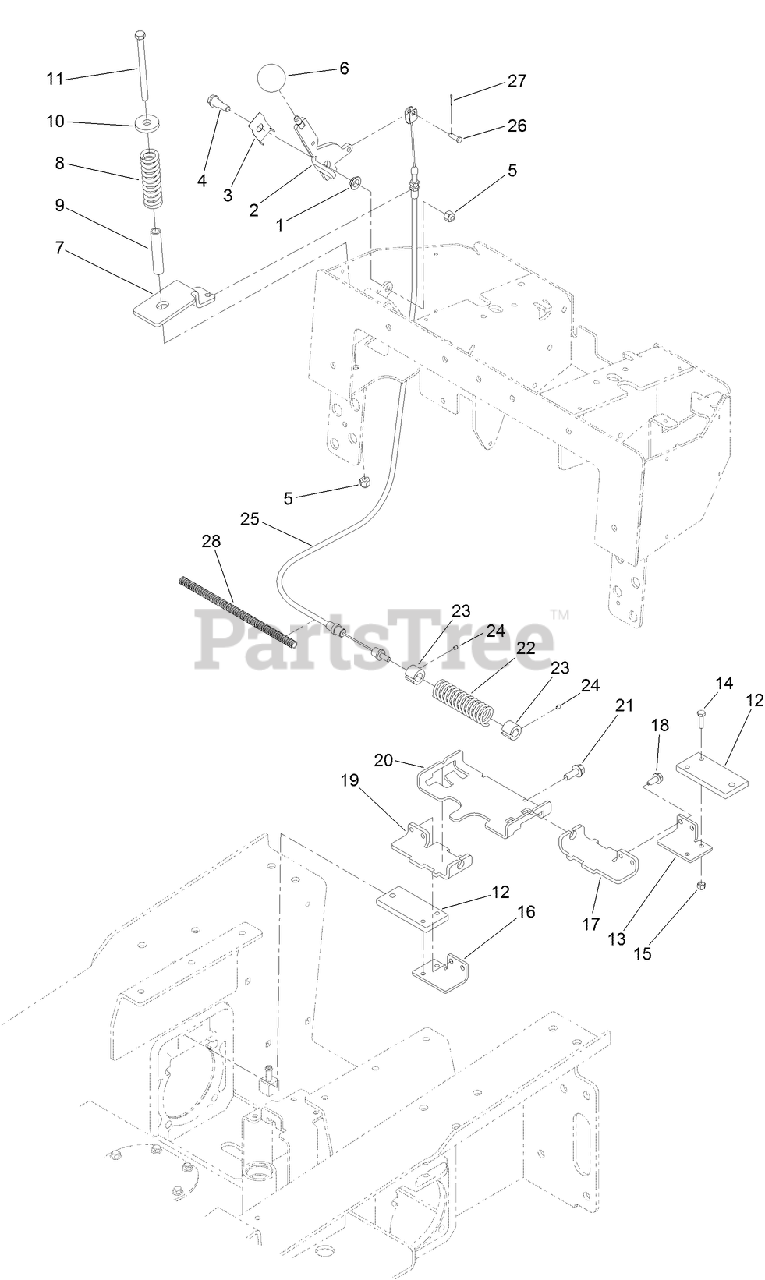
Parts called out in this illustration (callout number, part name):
1	BUSHING-FLANGE
2	HANDLE-BRAKE
3	SPRING-LEAF
4	BOLT-SHOULDER
5	NUT-LOCK, NI
7	BRACKET-CABLE, SPRING
8	SPRING-COMPRESSION
9	SPACER-SPRING
10	WASHER-HARDENED
11	SCREW-HH
12	PLATE-BRAKE
13	BAR-LINK, BRAKE LH
14	SCREW-HH
15	NUT-LOCK, NI
16	BAR-LINK, BRAKE RH
17	BRACKET-MOUNTING, BRAKE LH
18	SCREW-HWH
19	BRACKET-MOUNTING, BRAKE RH
20	SUPPORT-BAR, BRAKE
21	SCREW-HHF
23	TUBE-GUIDE
24	SCREW-HSH
25	CABLE-BRAKE
26	PIN-CLEVIS
27	PIN-COTTER
28	TUBE-CONVOLUTED
